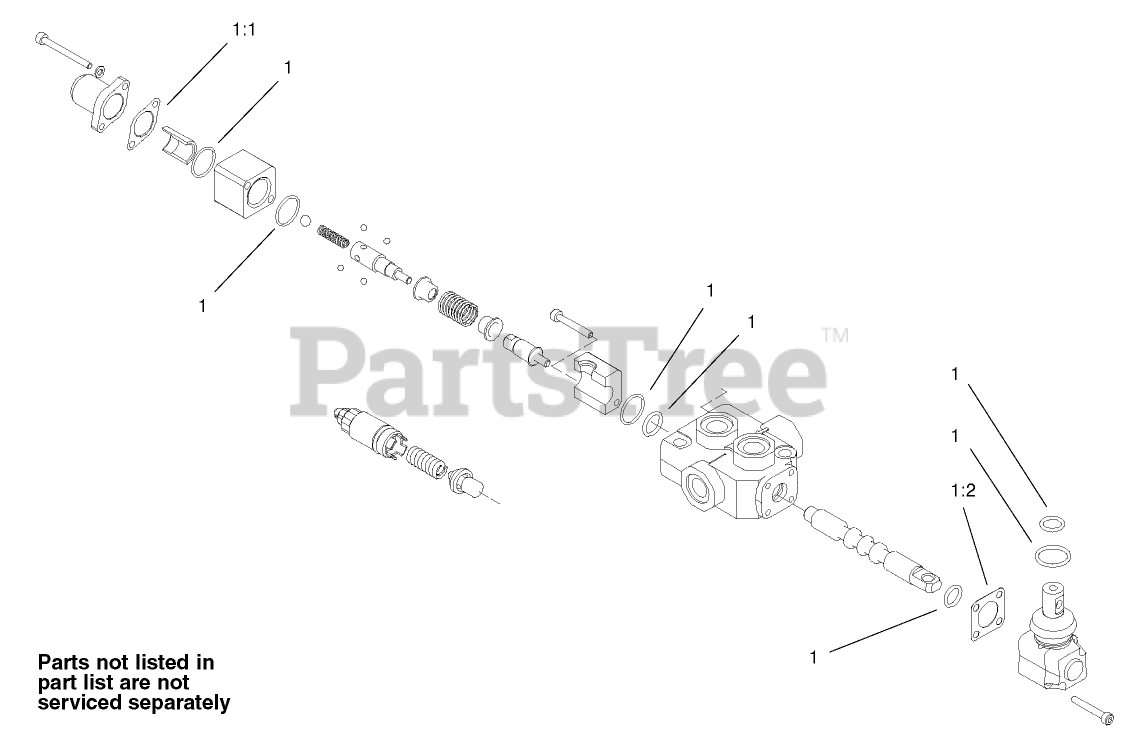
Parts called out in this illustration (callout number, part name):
1	SEAL KIT
1:1	GASKET
1:2	GASKET
